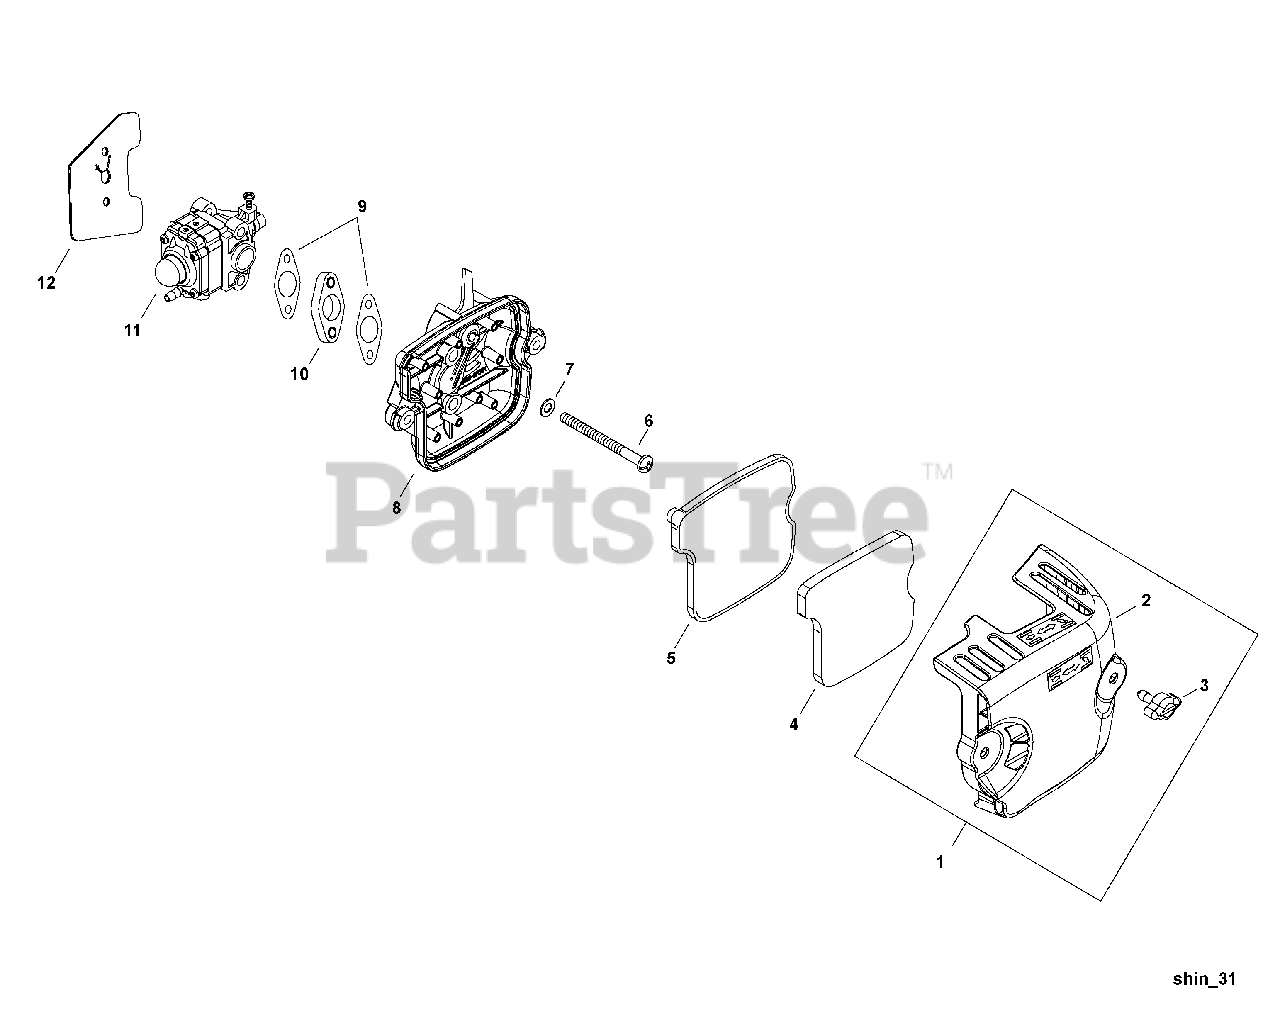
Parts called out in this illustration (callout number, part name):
1	AIR FILTER COVER ASSY
2	COVER, AIR FILTER
3	THUMBSCREW
4	PRE-FILTER -- FOAM
5	FILTER, AIR
6	SCREW - 5X70
7	WASHER - 5
8	CASE, AIR FILTER
9	GASKET, INTAKE
11	CARBURETOR RB-K100
12	GASKET, INTAKE
